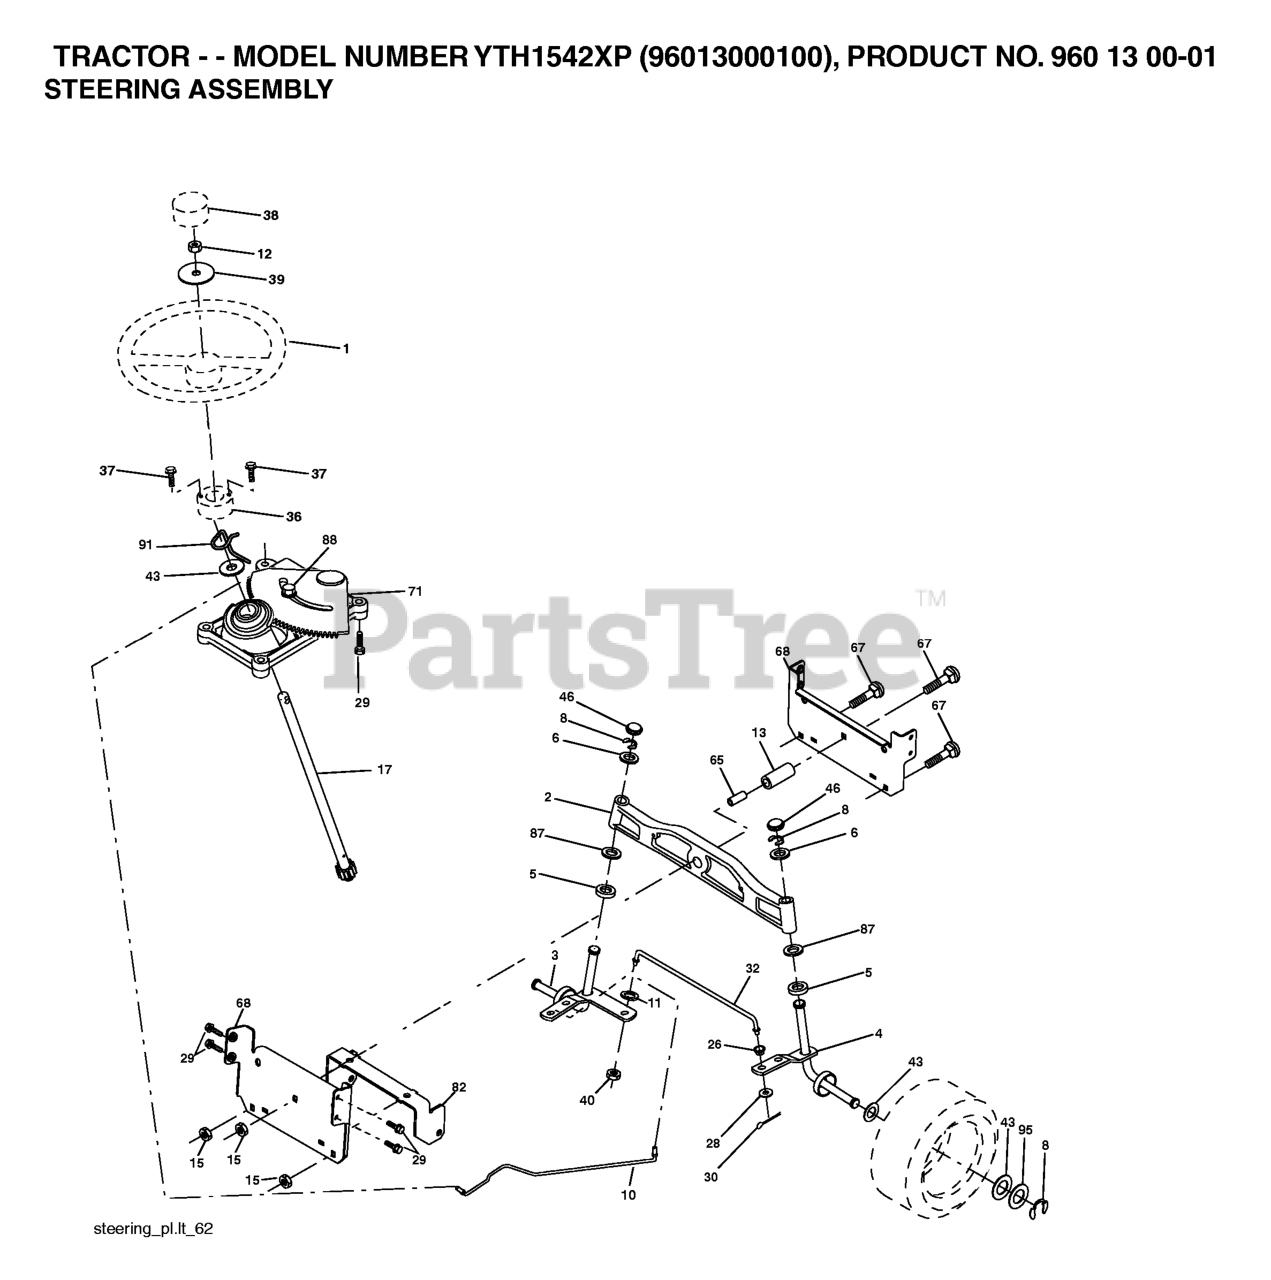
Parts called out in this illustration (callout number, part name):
1	STEERING WHEEL
2	AXLE ASSY FRONT
3	SPINDLE.ASM.LH.15"TIRES
4	SPINDLE.ASM.RH.15"TIRES
5	THRUST WASHER
10	DRAGLINK.15".TIRES.2001
11	WASHER, LOCK 3/8
12	NUT.HEX.1/2-20
13	TUBE, PIVOT AXLE
15	NUT
17	SHAFT ASM STRG
26	BUSHING.DRAGLINK (2 2)
28	WASHER
29	SCREW, 3/8-16X3/4
30	COTTER PIN
32	ROD.TIE.WIRE.FORM
36	BUSHING, STRG. BLK
37	SCREW.TT.#10-32X.5.3/8.FLANGE
38	INSERT.CAP.STRG.WH.GRAY
39	WASHER 9/16"ID, 2 3/8"OD
40	NUT CROWNLOCK 3/8-24
44	EXT, STEERING SHAFT
46	CAP.SPINDLE.BLACK
65	SPACER BRACE AXLE
67	BOLT CARRIAGE
68	BRACE.AXLE.15"TIRES
71	STEERING ASM
82	BRACKET
87	WASHER, FLAT .781 X 1 1/2"
88	BOLT, SHOULDER 7/16-20
91	CLIP.STEERING
95	WASHER.HARDENED
